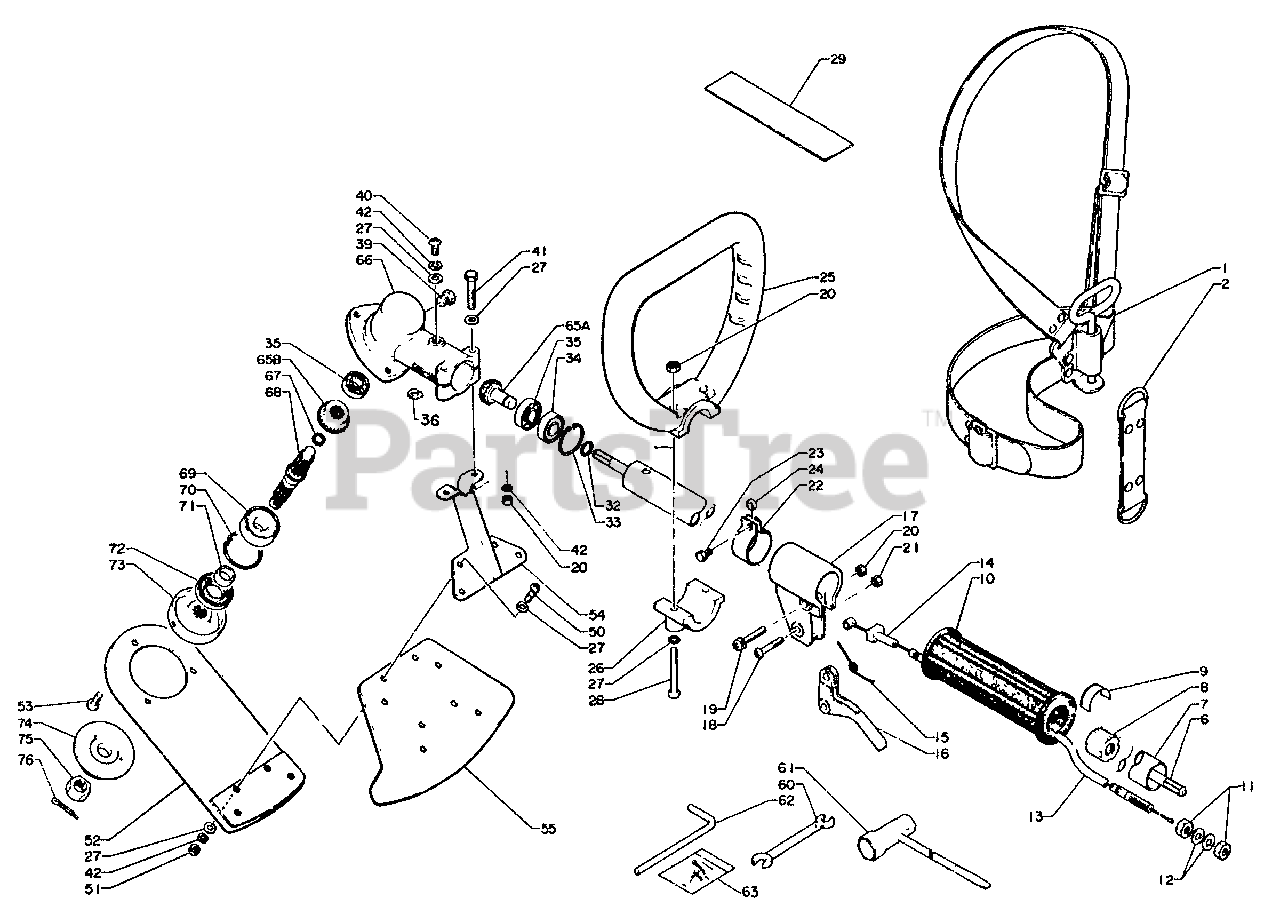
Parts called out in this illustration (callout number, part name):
1	SHOULDER STRAP ASSY
2	STRAP
6	DRIVESHAFT
7	MAIN PIPE ASSY
8	STOPPER
9	LABEL - ALIGNMENT
10	GRIP
12	WASHER - 6
13	CABLE, THROTTLE
14	GUIDE, CABLE
15	SPRING, TRIGGER
16	TRIGGER, THROTTLE
17	BRACKET, TRIGGER
18	SCREW - 5X30
19	SCREW - 5X30
21	LOCKNUT - 5
23	BOLT - 5X18
25	LOOP HANDLE ASSY
26	LOOP HANDLE ASSY
27	WASHER - 5
28	SCREW - 5X40
29	LABEL - CAUTION
32	RING, RETAINING
33	RING, RETAINING - 25
34	BEARING, BALL - 609
35	BEARING, BALL - 609
39	BOLT - 8X8
40	SCREW - 5X10
41	BOLT - 5X35
42	LOCKWASHER - 5
50	SCREW - 5X14
51	LOCKNUT - 5
54	BRACKET, SHIELD
55	SHIELD, DEBRIS
60	SPANNER - 8X10mm
61	T-WRENCH
62	LOCKING TOOL
63	PIN, SPLIT - 2X22
65	GEAR SET
65A	GEAR SET
65B	GEAR SET
66	CASE, GEAR
67	RING, RETAINING - 12
68	GEAR - SHAFT
69	BEARING, BALL - 6201
70	RING, RETAINING - 32
72	SEAL, OIL
73	ADAPTOR, BLADE - UPPER
74	ADAPTOR, BLADE - LOWER
75	NUT - 10 -- LEFT HAND
76	PIN, SPLIT - 2X22
